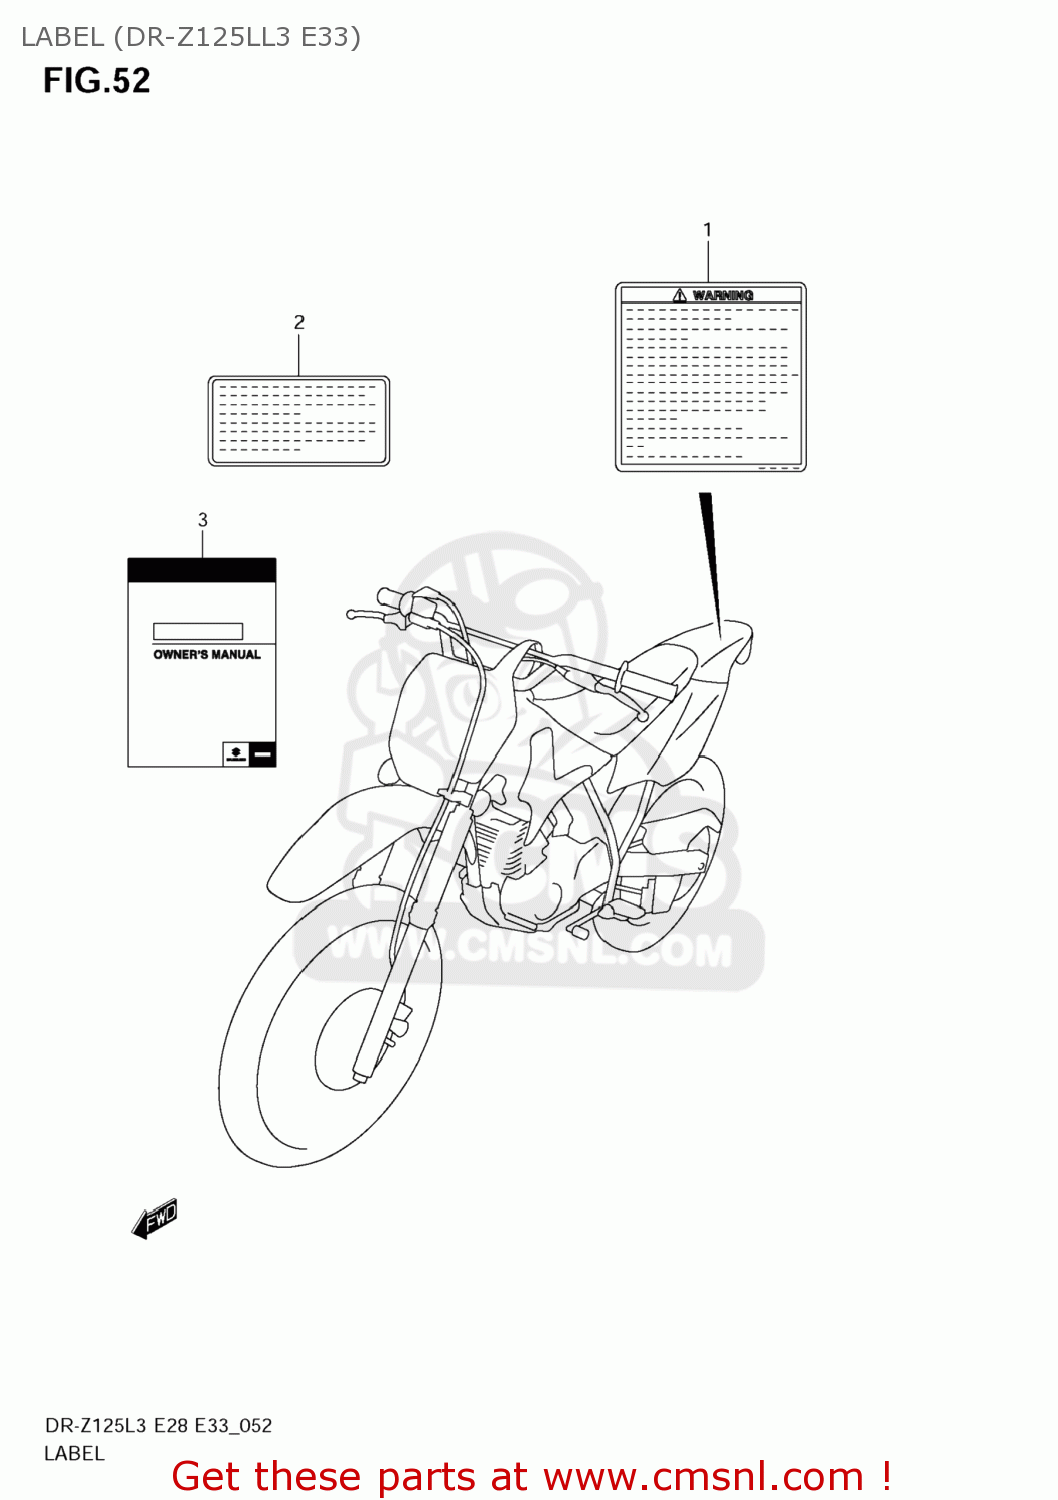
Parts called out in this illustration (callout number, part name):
1	LABEL,GENERAL WARNING
2	LABEL,MANUAL NOTICE
3	MANUAL,OWNER'S
